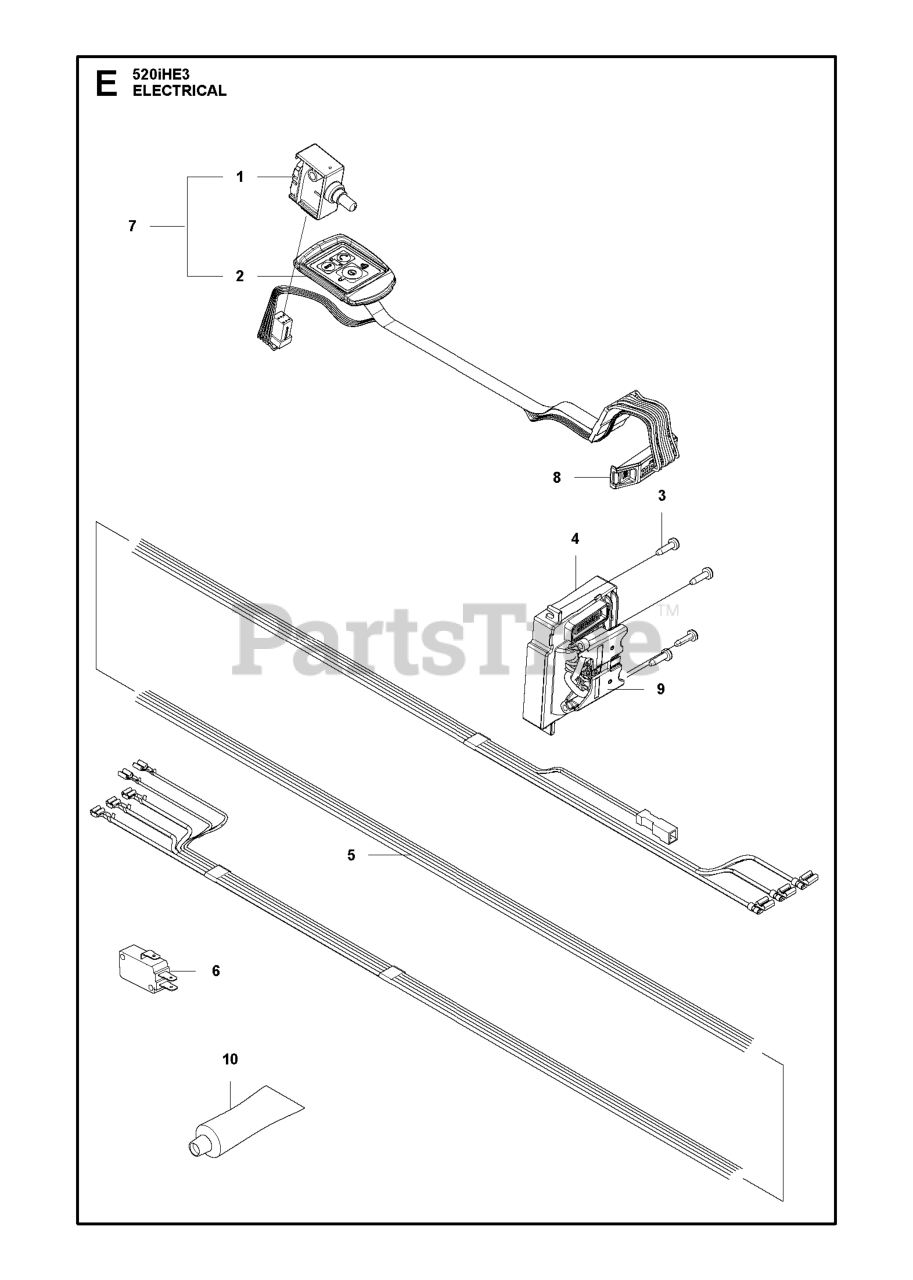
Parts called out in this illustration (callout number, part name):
1	TRIGGER SWITCH IPX4
2	WIRING ASSY POLE HEDGE MAIN
3	SCREW CITXPANT
4	CONTROL UNIT BLDC - 536LIHE3
5	WIRING ASSY POLE HEDGE MOTOR B
7	SWITCH KIT BATTERY POLE HEDGER
9	CONNECTOR BATTERY
10	GREASE 20G HEDGE TRIMMER GEAR
